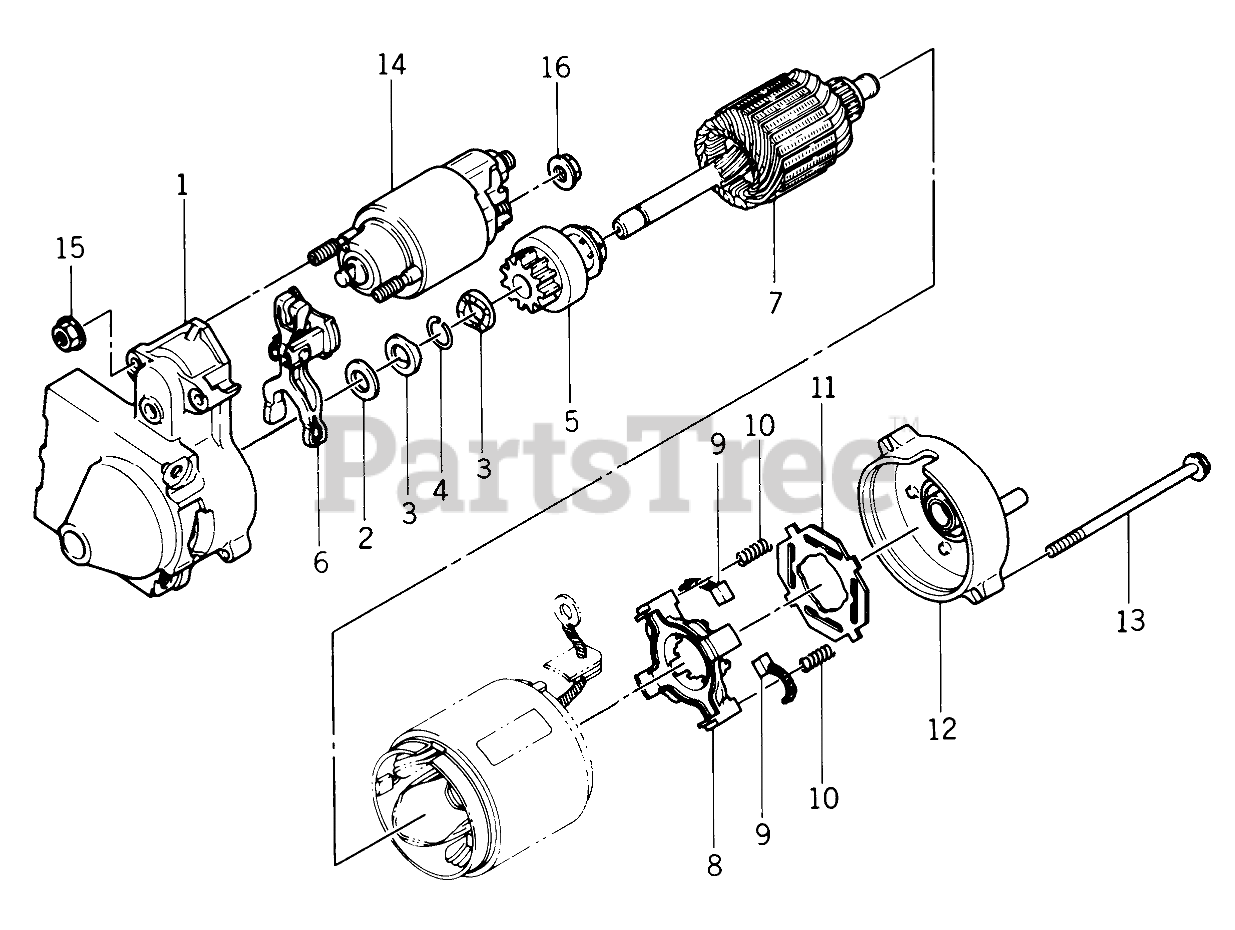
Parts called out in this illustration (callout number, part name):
1	COVER ASSY
2	WASHER
3	STOPPER
4	RING-SNAP
5	CLUTCH ASSY
6	LEVER-SHIFT
7	ARMATURE
8	HOLDER-BRUSH
9	BRUSH
10	SPRING-BRUSH
11	INSULATOR
12	COVER ASSY
14	SWITCH ASSY
